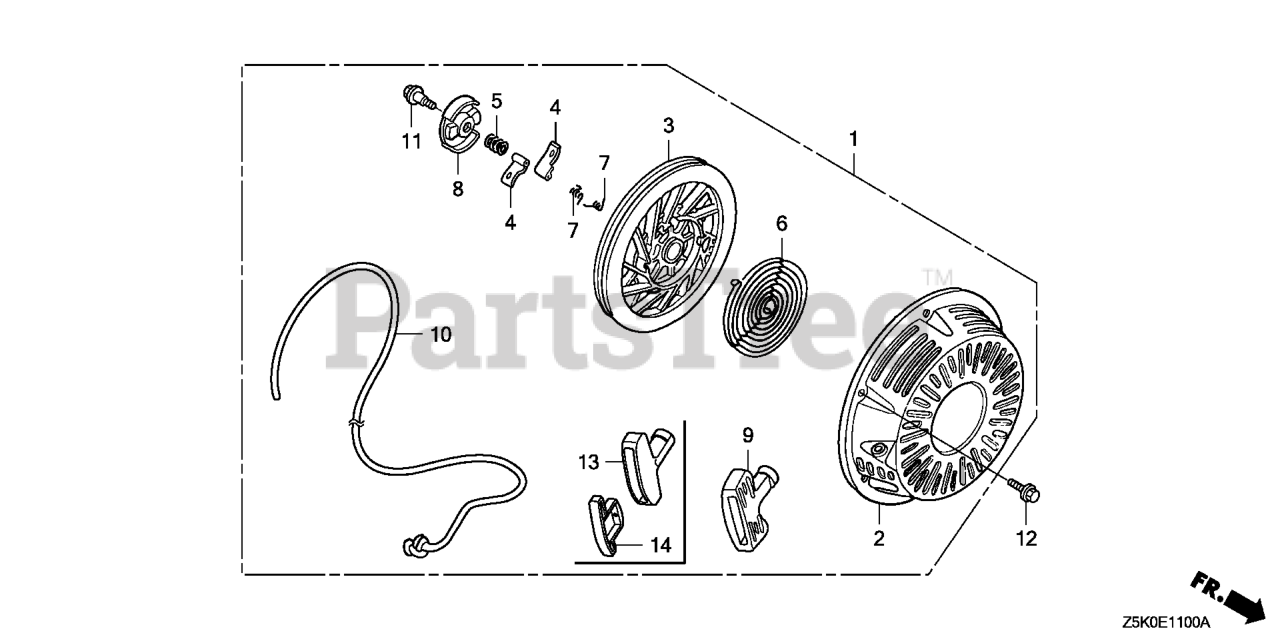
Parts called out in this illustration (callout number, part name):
1	STARTER ASSY. *R280*
1	STARTER ASSY., RECOIL *R280* (COO)(FOR U.S.A.) (POWER RED)
1	STARTER ASSY., RECOIL *NH1* (COO)(FOR U.S.A.) (BLACK)
2	CASE, RECOIL STARTER *NH1* (BLACK)
2	CASE, RECOIL STARTER *R280* (POWER RED)
3	PULLEY, RECOIL STARTER
4	RATCHET, STARTER
5	SPRING, FRICTION
6	SPRING, STARTER RETURN
7	SPRING, RATCHET
8	RETAINER, SPRING
10	ROPE, RECOIL STARTER (#5X55")
11	SCREW, CENTER
12	BOLT, FLANGE (6X10)
13	GRIP, STARTER
14	GRIP, REINFORCEMENT
